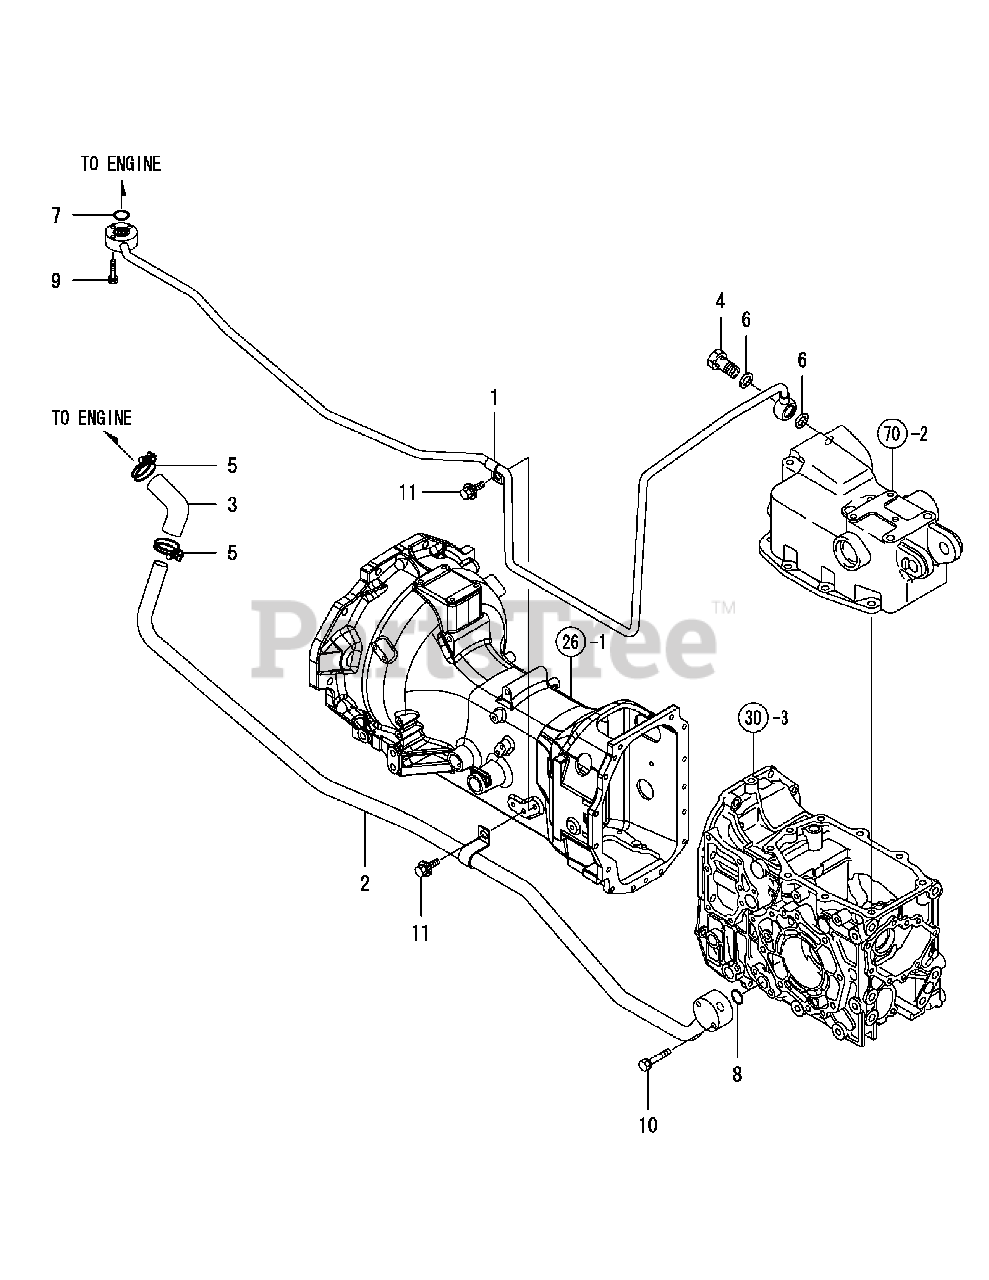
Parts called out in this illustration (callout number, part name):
1	Pipe, High Pressure
2	Pipe, Low Pressure
4	Connector Assy
7	O-Ring 1A P-20.0
8	O-Ring 1A P-22.0
